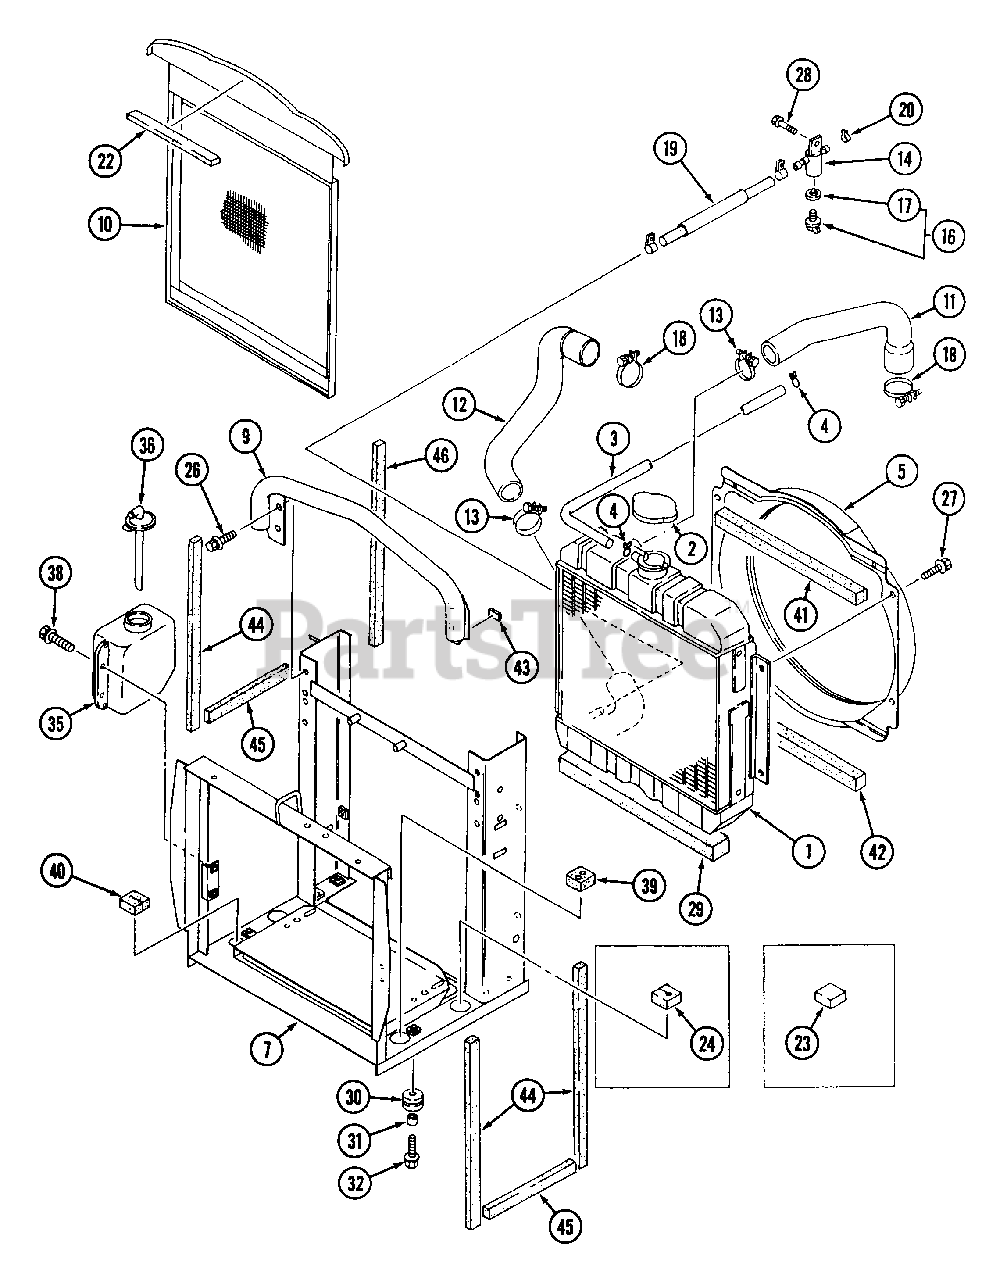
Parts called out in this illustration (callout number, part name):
1	Body, Radiator
7	Bracket, Radiator
16	Water Cock Ass'y.
18	Clip, Hose
19	Hose, Drain
24	Cushion
